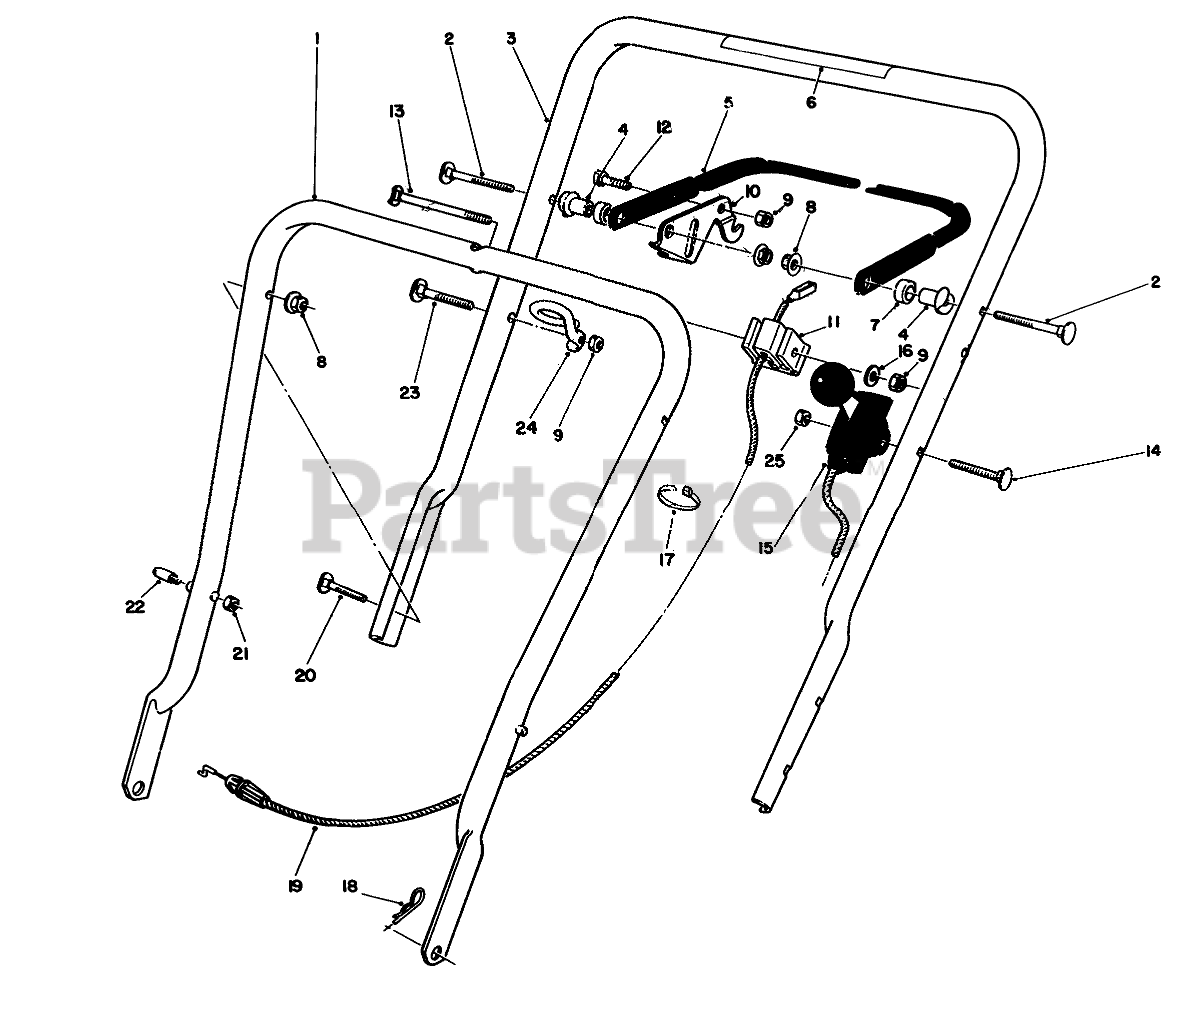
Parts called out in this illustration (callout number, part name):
1	LOWER HANDLE ASM
2	5/16-18 X 2 HNDLE SCREW
3	Handle-Upper (Incl. Ref. #6)
4	SPACER-SUPPORT
5	Bar-Control
6	DECAL - HANDLE
7	SPACER-NYLON
8	NUT-LOCK, NI
9	NUT-LOCK, NI
10	LEVER-CONTROL
11	SUPPORT-CABLE
12	SCREW-HH
13	HANDLE SCREW
14	SCREW-HANDLE
15	THROTTLE CONTROL
16	WASHER-FLAT
17	TIE-CABLE
18	PIN-COTTER, HAIR
19	OBS BRAKE CONTROL
20	SCREW
21	NUT-LOCK, NI
22	HANDLE PIN
23	HANDLE SCREW
24	Guide
25	NUT-LOCK, NI
